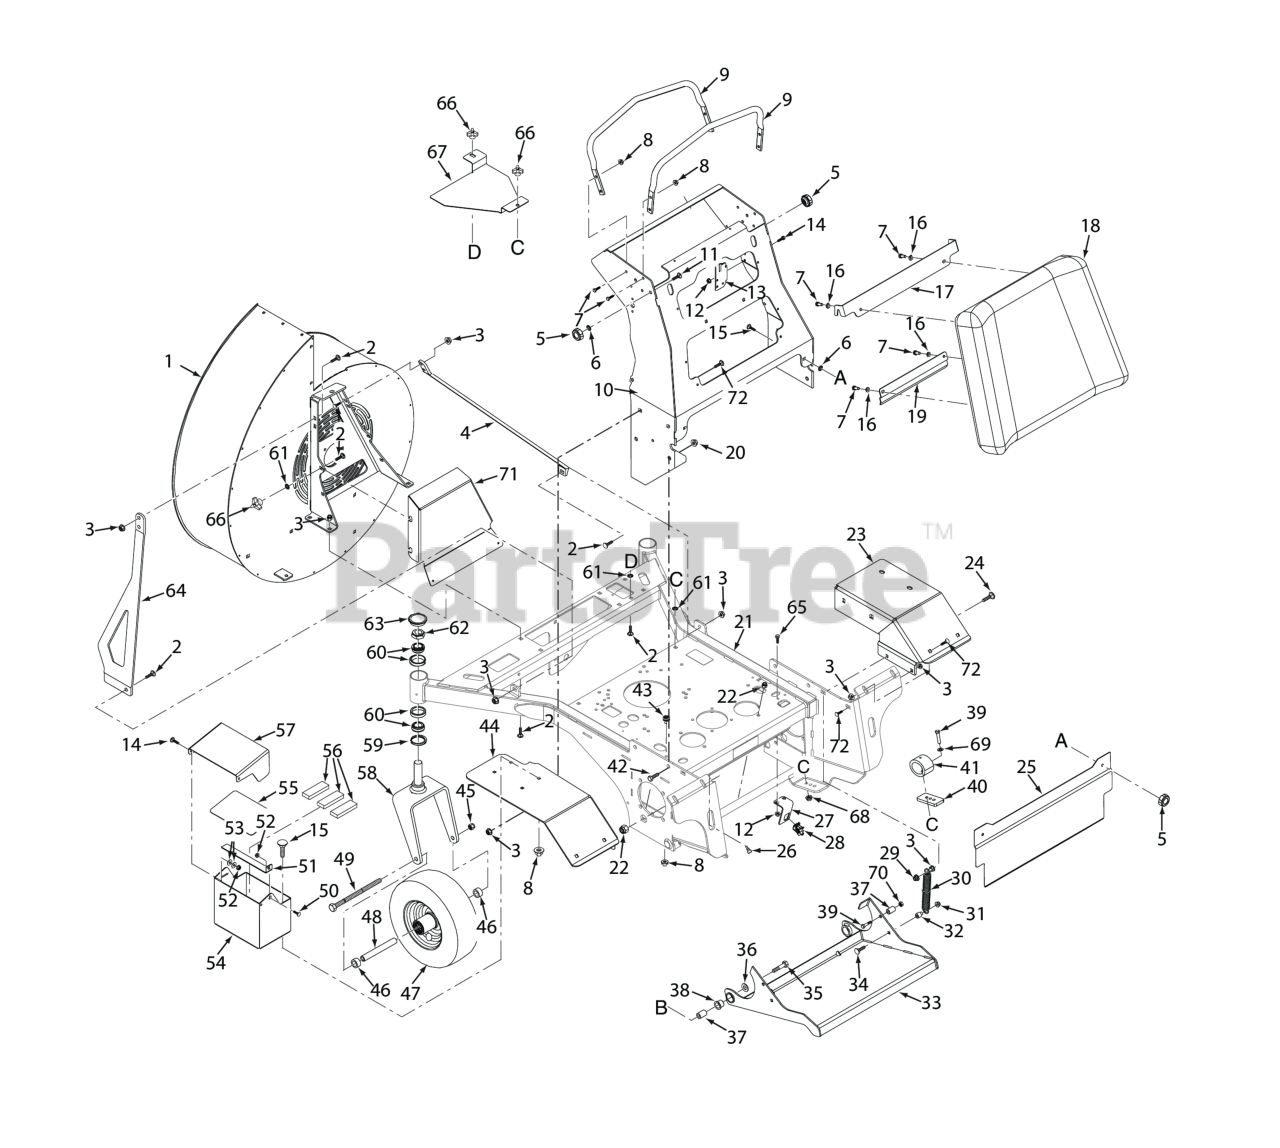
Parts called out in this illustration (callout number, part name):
1	Blower Housing, With Decal
2	Carriage Bolt, 3/8-16 x 1.0"
3	NUT, 3/8-16 SERRATED FLANGE HEX HEAD
4	RH Support Bar, Blower
5	Knob, 5/16-18
6	Nut, Push-On 5/16-18
7	BOLT, SERRATED FLANGE HEX HEAD 5/16-18 X 3/4"
8	Nut, Serrated Flange 5/16-18 (Right Front Engine Mounting, Briggs and Kohler Only)
9	Reference Bar
10	Handlebar Weldment, SVRII
11	Bolt, Carriage 5/16-18x1" (large frame units only)
12	NUT, 1/4-20 SERRATED FLANGE HEX HEAD
13	Bracket, Neutral Switch
14	BOLT, HEX HEAD, 1/4-20 X 3/4 GR.5
15	Bolt, 5/16-18 x .75 RHSN Carriage
16	Lockwasher, 5/16 (.317 x .586 x .078) Helical Spring
17	Bracket, Knee Pad - Upper
18	Operator Pad Assy, SVRII (INCL. 10,11,12,13)
19	Bracket, Knee Pad - Lower
20	Locknut, 1/2-13 Spiral Lock
21	Mainframe Assembly, With Decals
22	HEX NUT, ELASTIC STOP LOCK, 3/8-16
23	Fender, RH
24	Bolt, RDHD Carr. 3/8-16 x 1-1/2 (52" & 61")
25	Guard, Foot -SVRII
26	BUMPER, PLUG
27	Mounting Bracket, Footplate Switch
28	SWITCH, NEUTRAL INTERLOCK
29	Nut, Flange Elastic Stop Nut, 3/8-16
30	Spring,Counter Balance
31	Nut, Flange Head Elastic Stop 5/16-18
32	Spacer, Pump Dampener
33	Footplate Assy, SVRII (Incl. #35)
34	Bolt, Carriage 5/16-18 x 1-1/2"
35	Capscrew, Hex Head 3/8-16 x 2.0"
36	Flatwasher, 3/8" Special (.391 x .938 x .105)
37	Yoke, Front Caster Wheel
38	Bearing, Pivot
39	Bolt, Hex Head 3/8-16 x 1-3/4" (Kohler EFI)
40	Riser
41	Isolator, Footplate
42	Capscrew, 1/2-13 x 1" Serrated Flange Hex Head
43	Bumper, Rubber 5/16-18 x 5/8"
44	Fender, LH
45	HEX LOCKNUT, ELASTIC STOP, 1/2-13
46	Spacer, Caster Wheel
47	Wheel Assy, 61V, 72V (Incl. 20, 54, 55)
48	Sleeve, Caster Wheel (48 / 52)
49	Bolt, Hex Head 1/2-13 x 7-1/2" (48"/52")
50	Bolt, Carriage 1/4-20 x 1/2"
51	Battery Box Latch
52	HEX, NUT, ELASTIC STOP LOCK, 1/4-20
53	Flatwasher, 1/4" (.312 x .750 x .065")
54	Battery Box, Lower
55	Insulation, Battery Cover (Gas Only)
56	PAD, BATTERY SUPPORT
57	Battery Box, Upper
58	Yoke Weldment, (Black))
59	Seal, 2.00" O.D. x 1.625" Bore
60	BEARING & CUP, TAPERED SPINDLE
61	Nut, Push-On - 3/8" Dia.
62	Nut, Hex Elastic Stop 1.0"-14
63	Cap, Grease
64	LH Support Bar, Blower
65	Serr. Fl. Hex Head CPSCR, 1/4-20 x 3/4"
66	Wing Nut, 3/8-16 (Small) Top side
67	Belt Cover, Gearbox
68	Nut, Flange Elastic Stop Nut, 3/8-16
69	Flatwasher, 3/8 (.406 x .812 x .065)
70	Bolt, Hex Head 3/8-16 x 1" Ser. Flg.
71	Belt Cover, Blower
72	Bolt, Carriage 3/8-16 x 3/4"
